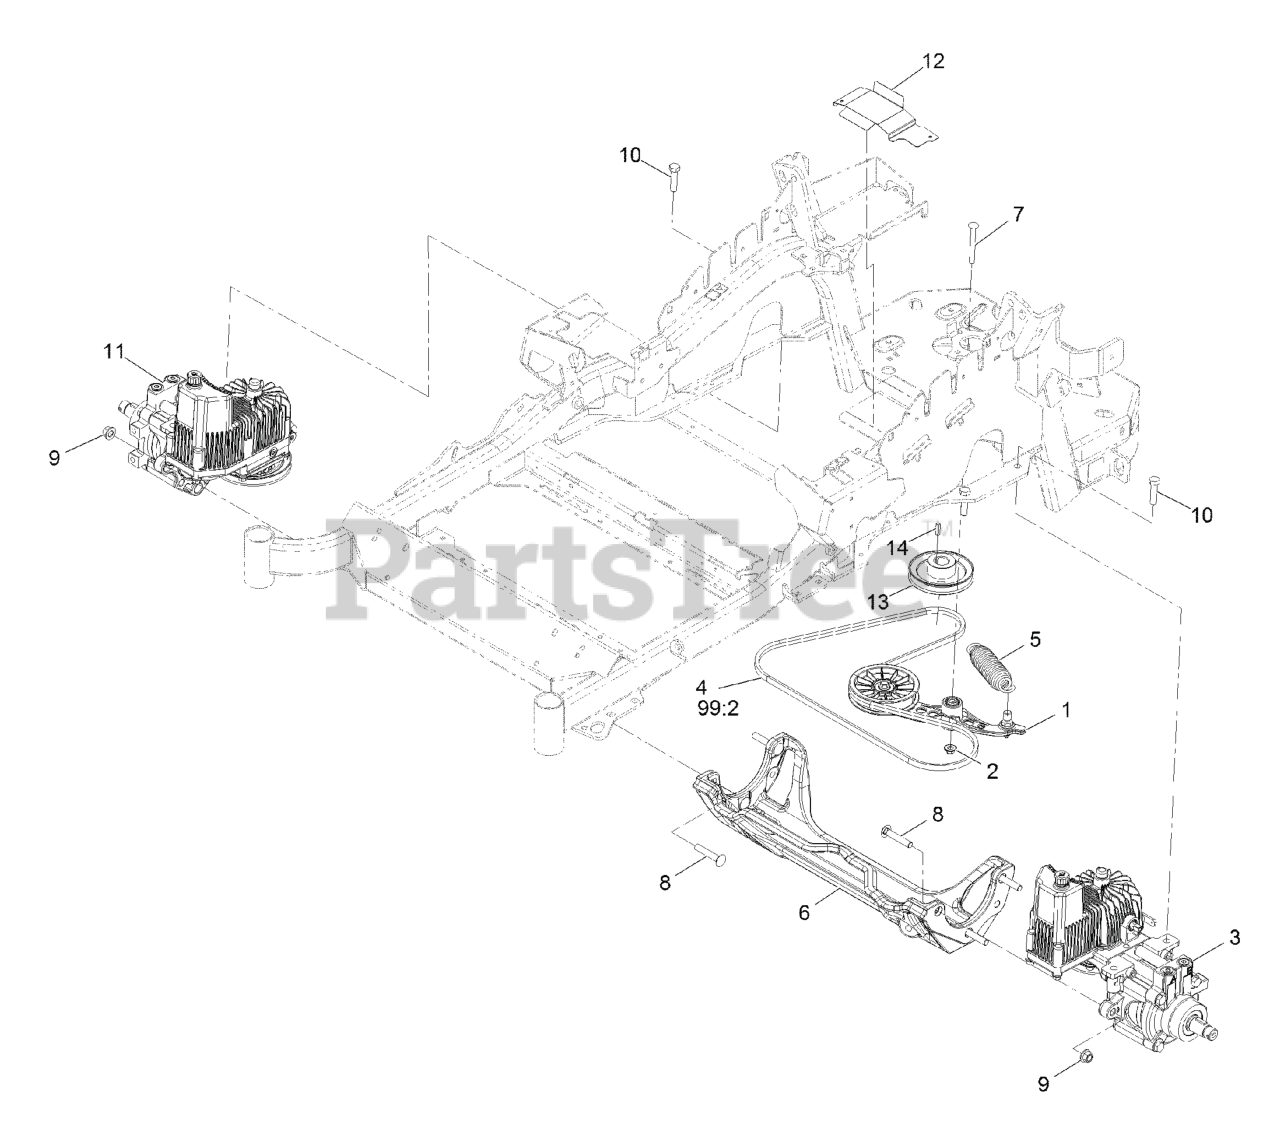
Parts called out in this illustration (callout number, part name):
1	PUMP IDLER ASM
2	Nut-Nyloc 3/8-16 Flg
3	LH HYDRO ASM (12CC W/ SHO
4	BELT
5	SPRING-EXTENSION
6	CRADLE-HYDRO
7	BOLT-SHOULDER, CARRIAGE 3/8-16 X 3 1/2
8	SCREW-CARR
9	Nut-Lock 1/2-13
10	SCREW-HH
11	RH HYDRO ASM (12CC W/ SHO
12	LH HYDRO GUARD ASM
12:2	DECAL-OIL, HYDRO
13	RH HYDRO GUARD ASM
13:2	DECAL-OIL, HYDRO
14	GUARD-HYDRO, REAR (LH)
15	GUARD-HYDRO, REAR (RH)
16	RIVET-POP
17	DEFLECTOR-AIR FLOW
18	SHEAVE
99:2	BELT
